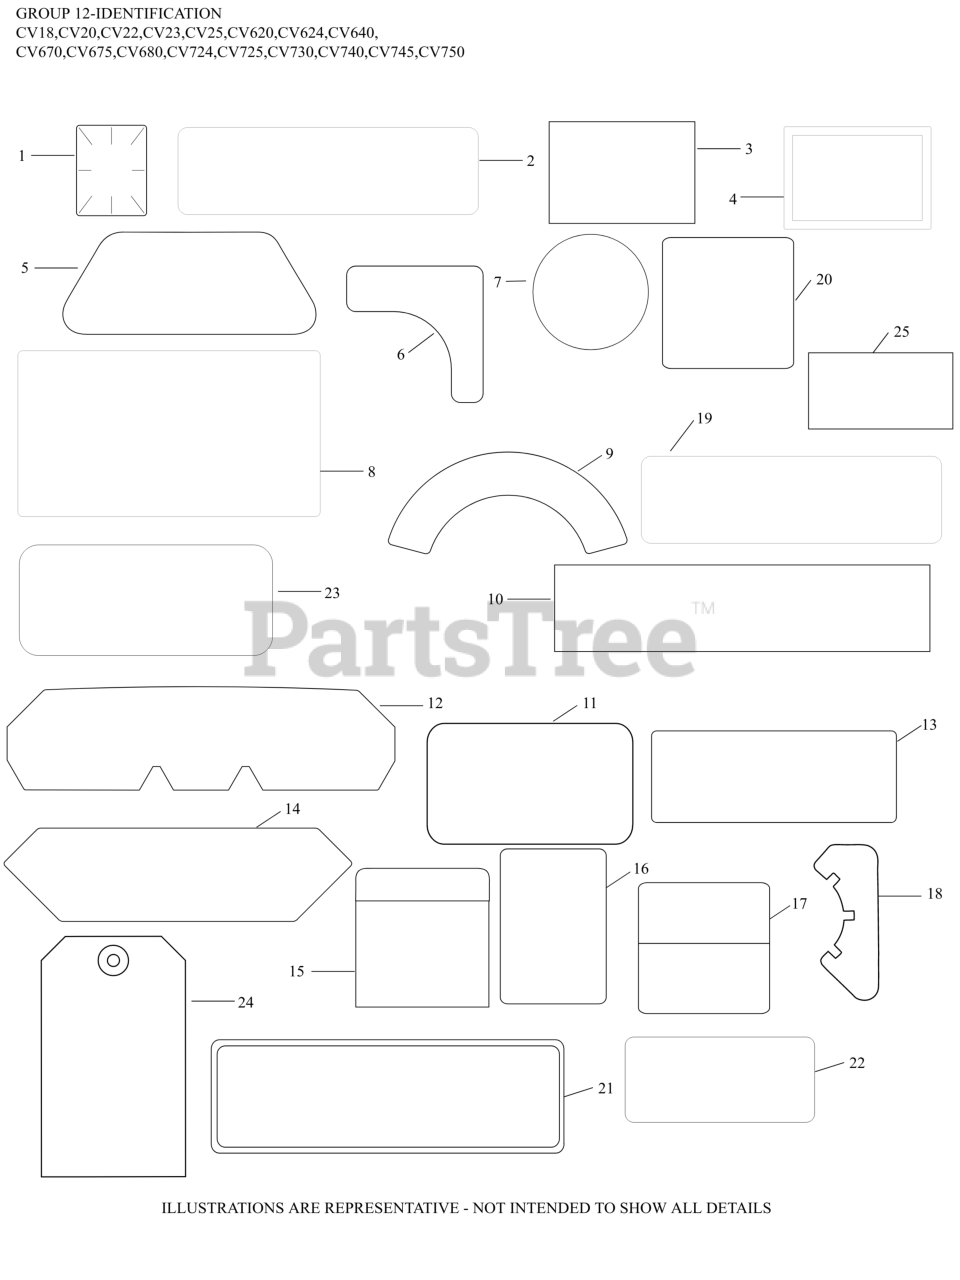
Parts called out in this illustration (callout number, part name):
1	LABEL, CLEAR LAMINATION
10	DECAL, STOPPING INSTRUCTION
19	DECAL LPAC, 20.5 HP/674cc/CV-CH640
24	TAG, HANG (OIL SENTRY)
